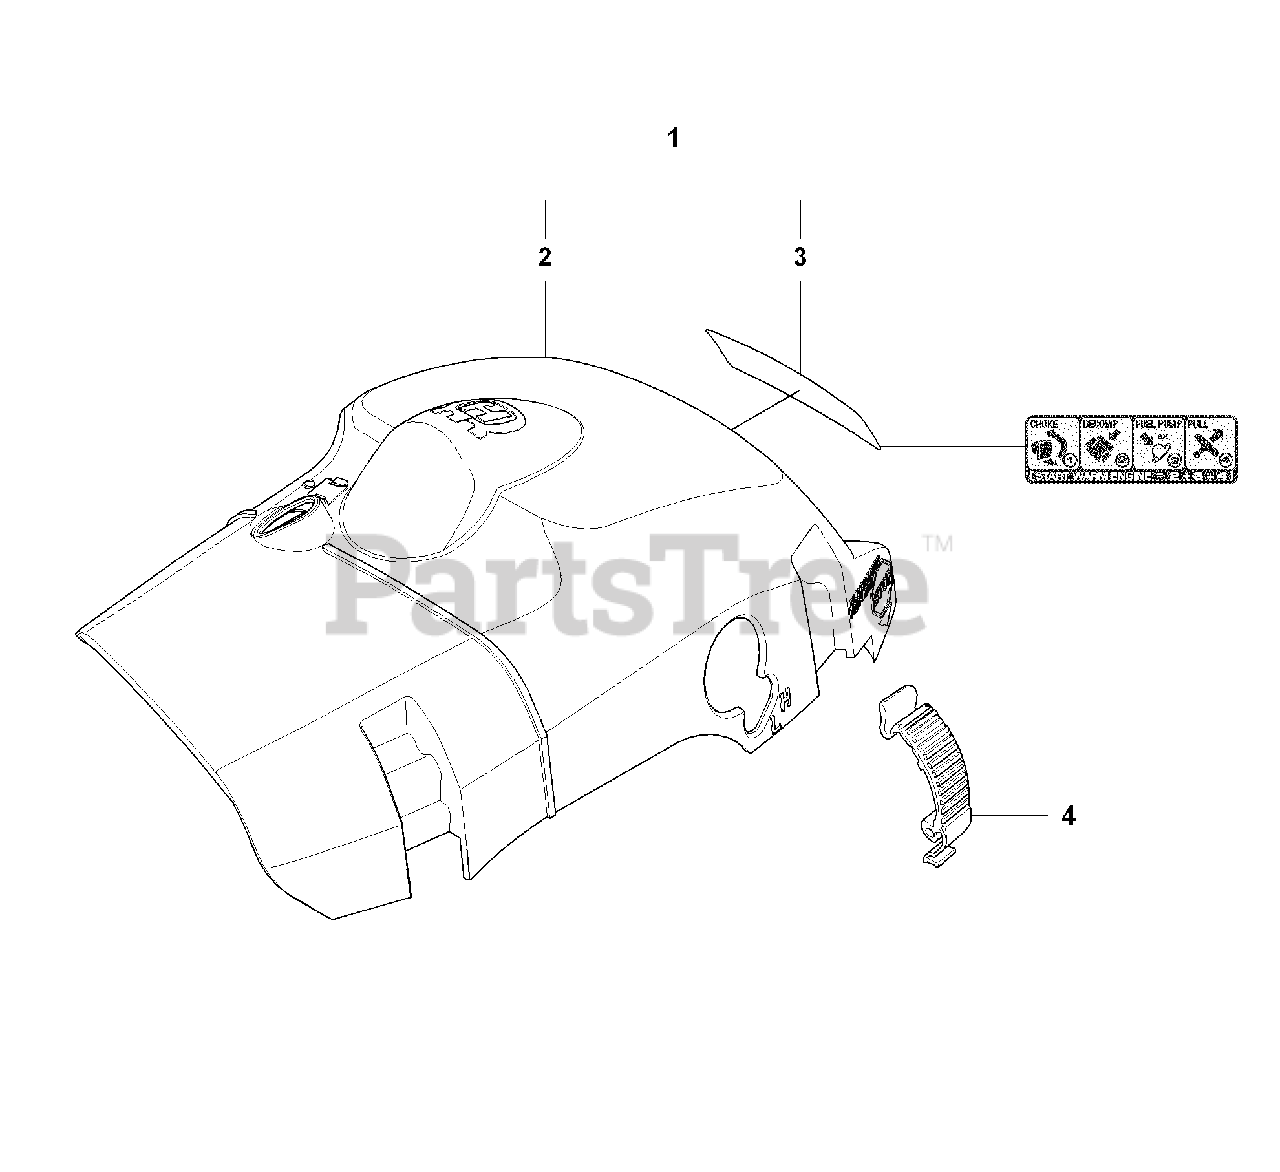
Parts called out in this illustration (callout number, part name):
1	%CYLINDER COVER ASSY
2	CYLINDER COVER
3	RP LABEL
4	BUCKLE ORANGE
